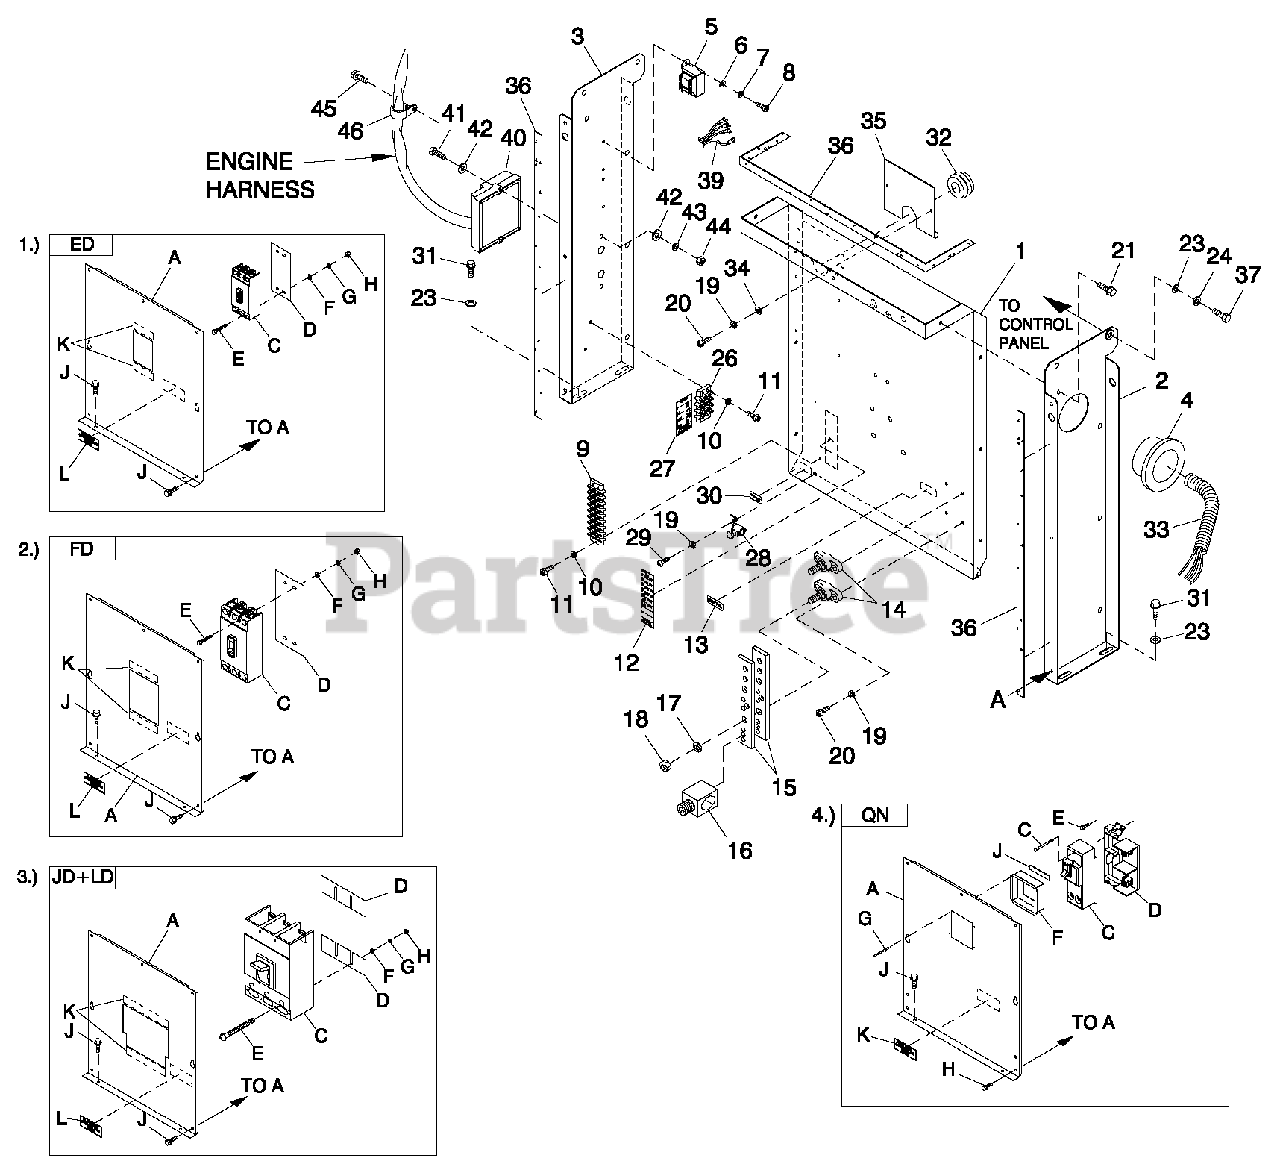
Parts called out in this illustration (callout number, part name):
1	PAN CB CONN BOX
1	UL CIRCUIT BREAKER (ED)
2	STAND RH CONTROL
2	UL CIRCUIT BREAKER (FD)
3	STAND LH CONTROL
3	UL CIRCUIT BREAKER (JD+LD)
4	BUSHING SNAP SB-2.5-31
4	UL CIRCUIT BREAKER (QN)
5	XFMR DUAL 120V/16V (FOR 120/240V & 277/480V UNITS)
6	WASHER FLAT M4
7	WASHER LOCK #8-M4
8	SCREW PHTTM4-0.7X 10 ZYC
9	BLOCK TERM 20A 8 X 6 X 1100V
10	WASHER LOCK #6
11	SCREW PHTT #6-32X1/2 ZYC
12	DECAL UTIL SENSE/CUST CONN
13	DECAL NEUTRAL
14	JUNCTION BLOCK 3/8-16
15	BUS BAR NEUTRAL BLOCK 390
16	LUG SLDLSS 600/250-1/0 X 1/4-28
17	WASHER LOCK 3/8
18	NUT HEX 3/8-16 STEEL
19	WASHER LOCK M5
20	SCREW PHTT M5-0.8X 16 ZYC
21	SC REW THFM6-1X16NWA Z/JS
23	WASHER FLAT 1/4-M6 ZINC
24	WASHER LOCK M6-1/4
26	BLOCK TERM 20A 6 X 3 X 1100V
27	DECAL CUST CONN 120V UTILITY
28	LUG SLDLSS #6-14X 13/64 CU
29	SCREW HHTT #10-32X3/8 CZ
30	DECAL GROUND LUG
31	SCREW HHTT M6-1.0X16ZYC
32	GROMMET 1.25 X .25 X .75
33	CONDUIT FLEX 2.0" ID (36" LG)
34	WASHER FLAT M5
35	PLATE WIRE SNGLGALV
36	TAPE ELEC 1/2 FOAM (AS REQ'D)
37	SCREW HHC M6-1.0X 16 G8.8
39	HARNESS, TRANSFORMERADAPTER
40	ASSY PCB IGN MOD 4.2L
41	SCREW PPHM #10/32X2
42	WASHER FLAT #10 ZINC
43	WASHER LOCK #10
44	NUT HEX #10-32 STEEL
45	SC REW THFM6-1X16NWA Z/JS
46	CLAMP VINYL 1.06 X.406 Z
47	SEAL WEATHER .45"DIA
A	COVER ED CB SHORT STND
C	CB 0050A 3P 480V S ED4 LL
D	INSULATOR CBS(ED-3P)
E	SCREW RHM #10-32X4-1/2
F	WASHER FLAT #10 ZINC
G	WASHER LOCK #10
H	NUT HEX #10-32 STEEL
J	SC REW THFM6-1X16NWA Z/JS
K	TAPE ELEC 1/2 FOAM (AS REQ'D)
L	DECAL CUSTOMER CONNECT INSIDE
A	COVER CB CONN BOX
C	CB 0150A3P 600V SFD6 LL
D	INSULATOR CB FD FRAME 30MIL
E	SCREW SHC 1/4-20 X 4.5 G8.8 NZ
F	WASHER FLAT 1/4-M6 ZINC
G	WASHER LOCK M6-1/4
H	NUT HEX 1/4-20 STEEL
J	SCREW THF M6-1 X 16 N WA Z/JS
K	TAP E E LEC 1 /2 FOAM (AS REQ' D)
A	COVER JD/LD CB SHRT STAND
C	CB 0300A 3P 600V S JD6LL
D	INSULATOR CIRCUIT BR. JD/LD
E	SCREW RHM 1/4-20X3
A	COVER QNFRMCB
C	CB 0150A 2P 240V S QN2 LL
D	BASE, QN CIRCUIT BREAKER
E	SCREW HHTT M5-0.8X 10 BP
F	COVER QNCB DISH
G	RIVET POP .125 X .275 SS
H	SCREW THF M6-1X16 N WA Z/JS
J	TAP E E LEC 1 /2 FOAM (AS REQ' D)
K	DECAL CUSTOMER CONNECT INSIDE
